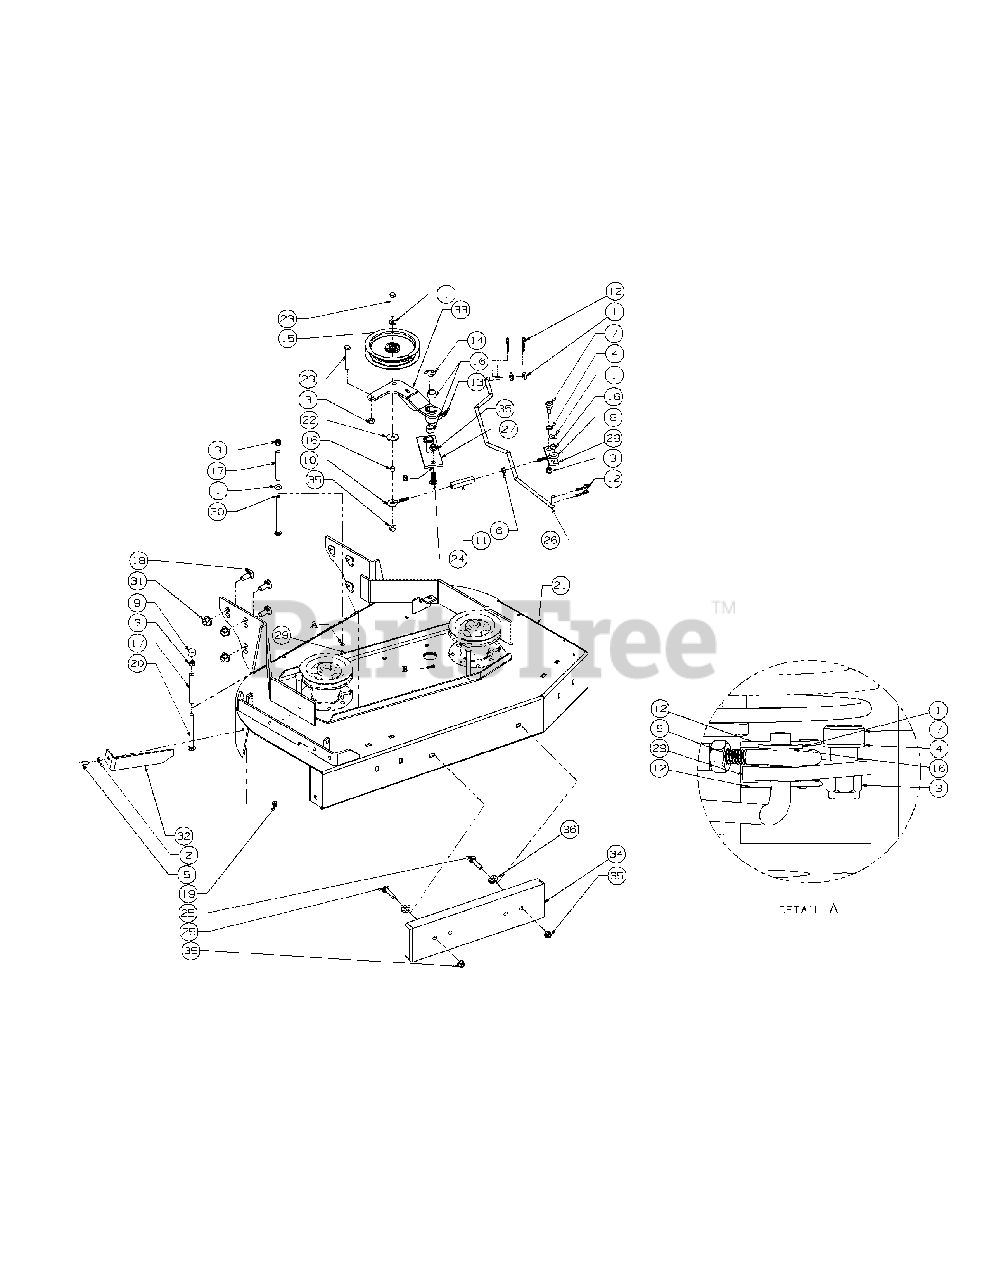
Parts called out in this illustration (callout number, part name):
1	Flat Washer, 3/8 Zinc
2	Flat Washer, 5/16 Zinc
3	Lock Nut, Nylon Insert, 3/8-16
4	Shim Washer
5	Hex Cap Screw, 5/16-18 x .75
6	Hex Nut, 5/16-18
7	Shoulder Bolt
8	Eye Bolt, Right Hand
9	Cap, Black Vinyl
10	Eye Bolt, Left Hand
11	Turnbuckle
12	Hair Pin, 3/8"-1/2"
13	Grease Fitting, 45°, 1/4-28
14	E-Ring, Retainer
15	Idler Deck Take-up
16	Turnbuckle, Sleeve
17	Spacer, Belt Guide
18	Carriage Bolt, 1/2-13 x 1-1/4
19	Nut, Hex Flange Lock, 5/16-18
20	Carriage Bolt, 3/8-16 x 4.5
22	Washer, 1.25 x .411 x .100
23	Hex Cap Screw, 3/8-16 x 2.75
24	Carriage Bolt, 3/8-16 x 1-1/4
25	Carriage Bolt, 3/8-16 x 1-1/2
26	Rod Clutch Link
27	Idler Base
29	Deck Stiffener
30	Carriage Bolt, 3/8-16 x 5.00
31	Nut, Flange Lock, 1/2-13
33	Idler Arm
35	Flange Lock Hex Nut, 3/8-16
36	Push Retainer
